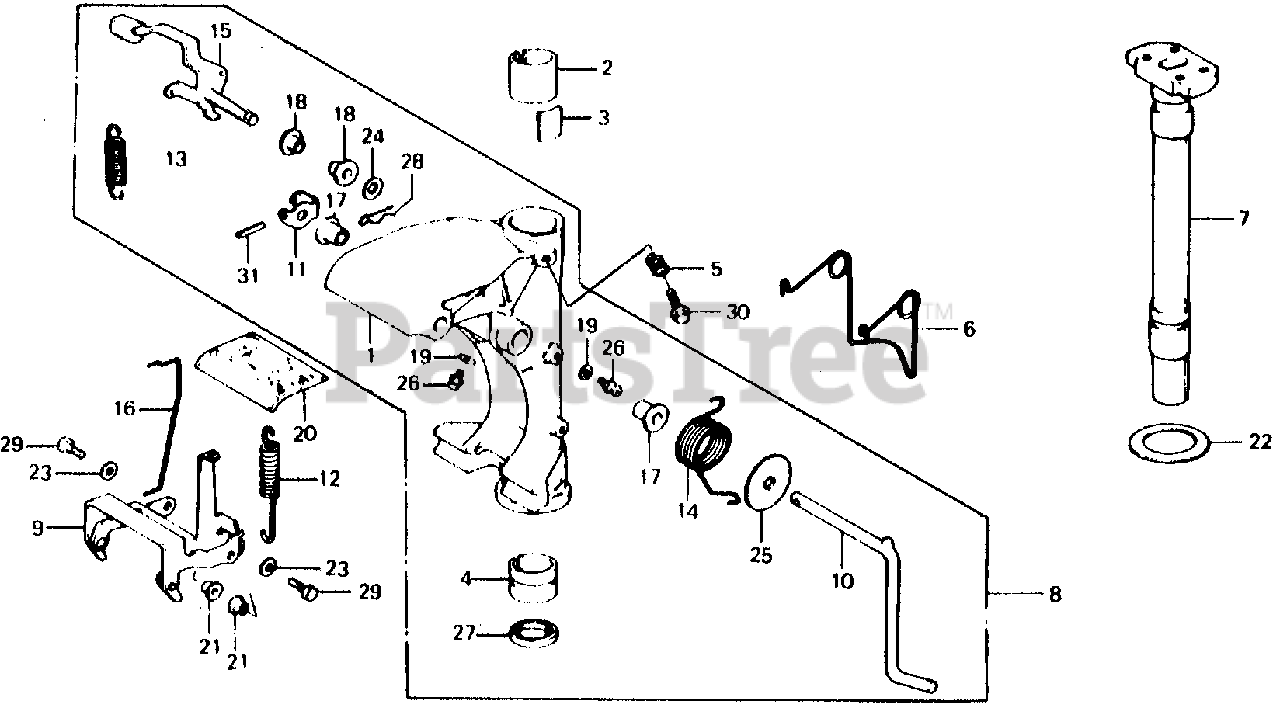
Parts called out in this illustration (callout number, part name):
1	CASE, SWIVEL *B9* (ATLANTIS BLUE)
2	LINER, SWIVEL CASE
3	BLOCK, FRICTION
4	BUSH, SWIVEL SHAFT
5	SPRING, FRICTION ADJUSTING
6	SPRING, HOOK RETURN (NOT AVAILABLE)
7	SHAFT, SWIVEL *B9* (ATLANTIS BLUE)
8	CASE, SWIVEL *B9* (ATLANTIS BLUE)
9	LOCK, REVERSE
10	LINK, TILT (NOT AVAILABLE)
11	BRACKET, TILT LEVER (NOT AVAILABLE)
12	SPRING, REVERSE LOCK
13	SPRING, TILT LEVER (NOT AVAILABLE)
14	SPRING, TILT LINK (NOT AVAILABLE)
15	LEVER, TILT (NOT AVAILABLE)
16	ROD, RELEASE SWIVEL CASE (NOT AVAILABLE)
17	BUSH, TILT LEVER (NOT AVAILABLE)
18	BUSH B, TILT LEVER (NOT AVAILABLE)
19	WASHER (6X11)
20	PLATE, SETTING CAUTION (NOT AVAILABLE)
21	COLLAR (6MM) (NOT AVAILABLE)
22	WASHER, THRUST
24	WASHER, PLAIN (10MM)
25	WASHER, PLAIN (10MM) (NOT AVAILABLE)
26	NIPPLE, GREASE
27	OIL SEAL (32X37X7) (NOK)
28	PIN, LOCK (10MM)
29	BOLT, HEX. (6X16)
30	BOLT, HEX. (8X20) (NOT AVAILABLE)
31	PIN, SPRING (4X25)
